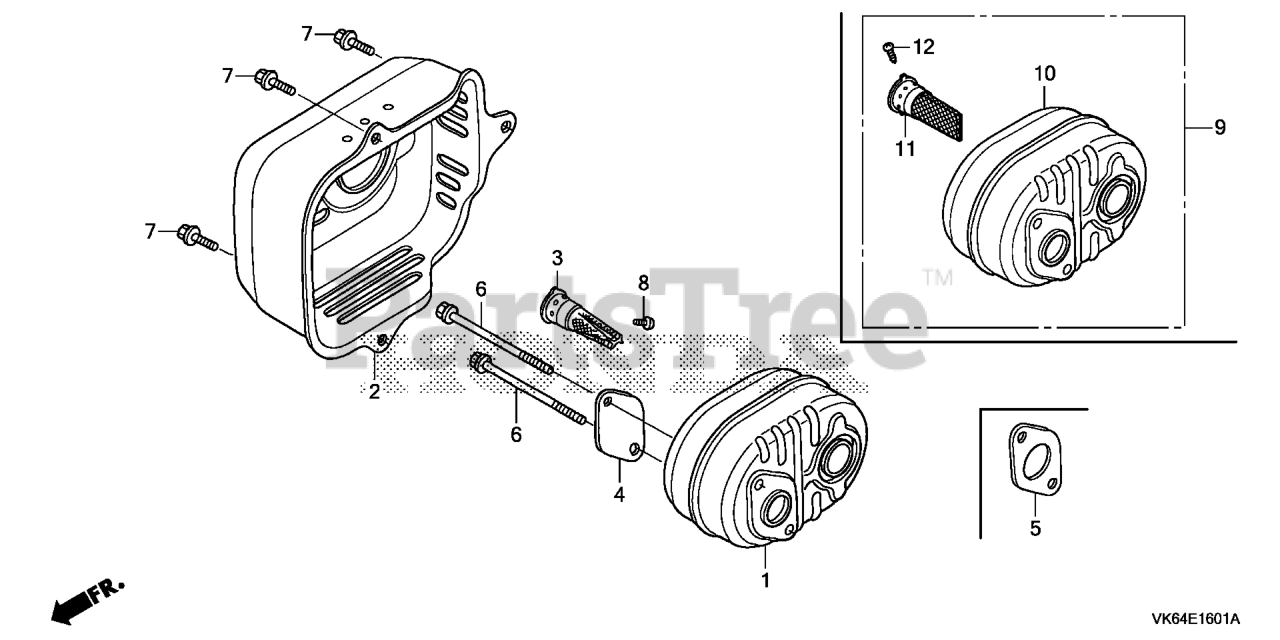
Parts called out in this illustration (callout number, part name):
2	PROTECTOR, MUFFLER
3	ARRESTER, SPARK (TO 1207644)
4	PLATE, ARRESTER NUMBER (TO INSTALL OPTIONAL SPARK ARRESTER)
5	GASKET, MUFFLER
6	BOLT, FLANGE (6X79) (CT200)
7	BOLT, FLANGE (6X12) (CT200)
8	SCREW, TAPPING (4X6) (TO INSTALL OPTIONAL SPARK ARRESTER)
9	MUFFLER ASSY. (ARRESTER)
10	MUFFLER
11	ARRESTER, SPARK
12	SCREW, TAPPING (4X6) (TO INSTALL OPTIONAL SPARK ARRESTER)
